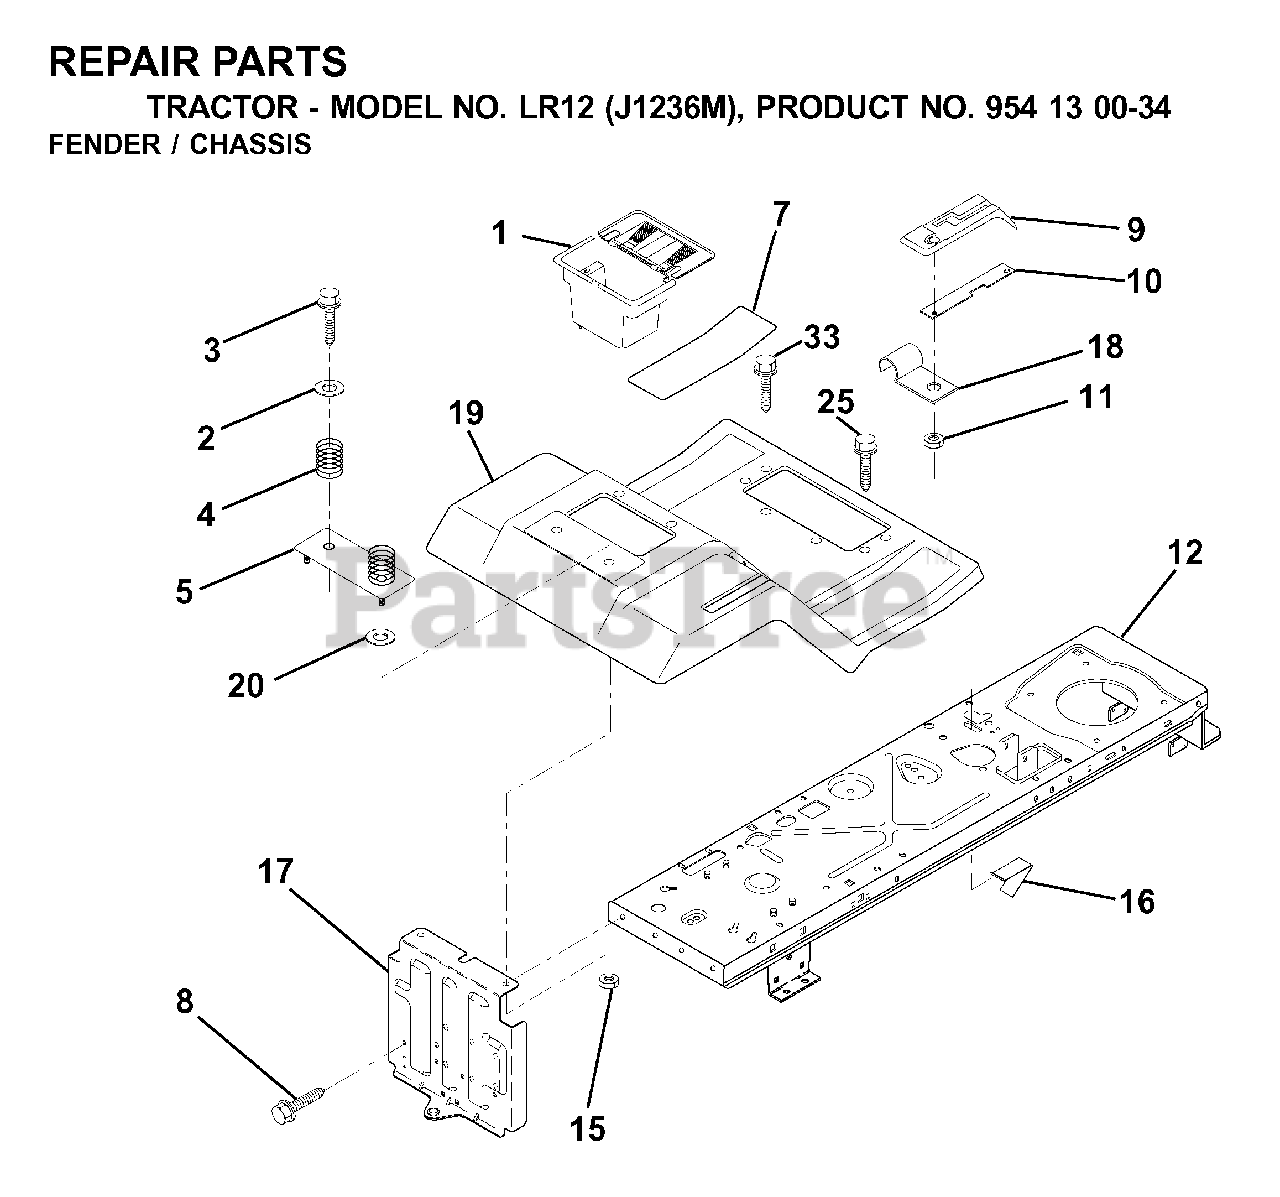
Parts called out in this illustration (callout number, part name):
1	CASE BATTERY MECH HINGE
3	SCREW
4	SPRING COMPRESSION
7	PAD FOOTREST
8	SCREW 5/16"
10	BAR, SHIFT LOCK
18	CLIP,INSULATOR
20	WASHER
